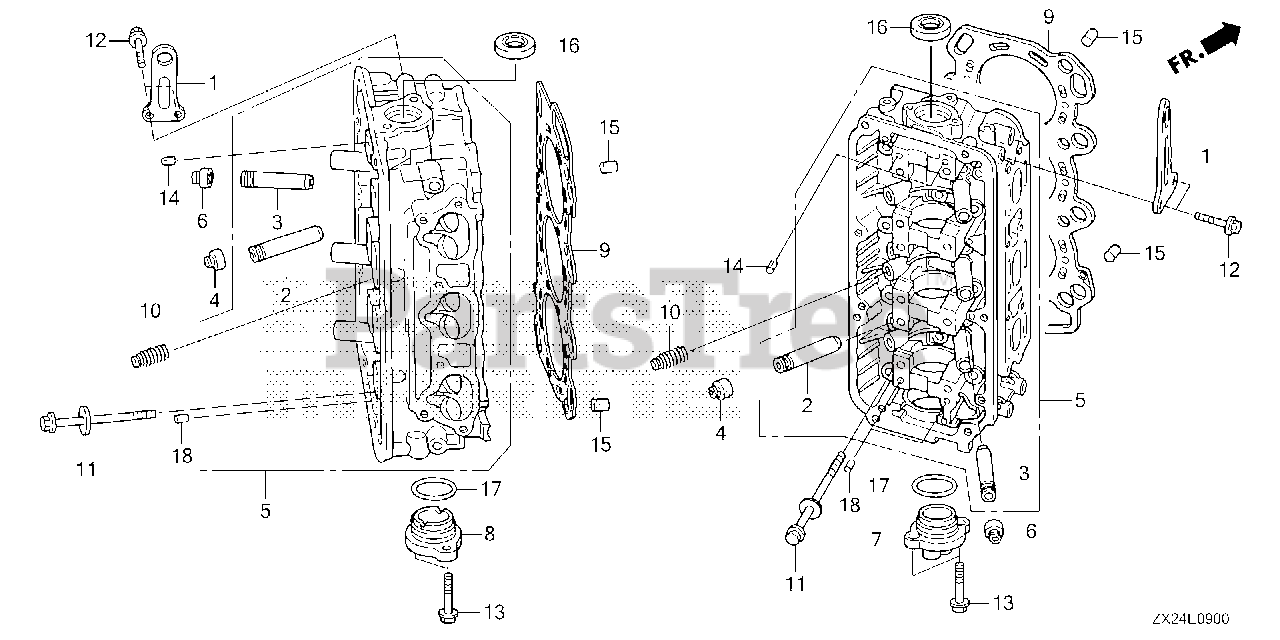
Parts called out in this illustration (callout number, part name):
1	HANGER, ENGINE
2	GUIDE, VALVE (OVER SIZE)
3	GUIDE, EX. VALVE (OVER SIZE)
4	SEAL A, VALVE STEM (NOK)
5	CYLINDER HEAD *NH8* (DARK GRAY)
6	SEAL B, VALVE STEM (NOK)
7	COVER, R. CAMSHAFT THRUST
8	COVER, L. CAMSHAFT THRUST
9	GASKET, CYLINDER HEAD (NIPPON LEAKLESS)
10	MOTION, LOST
11	BOLT-WASHER (12X163)
12	BOLT, FLANGE (8X20)
13	BOLT, FLANGE (8X28)
14	PIN, DOWEL (6X10)
15	PIN, DOWEL (16X22)
16	OIL SEAL (39X53X8) (NOK)
17	O-RING (48.5X2.4)
18	PIN B, DOWEL (6X10)
